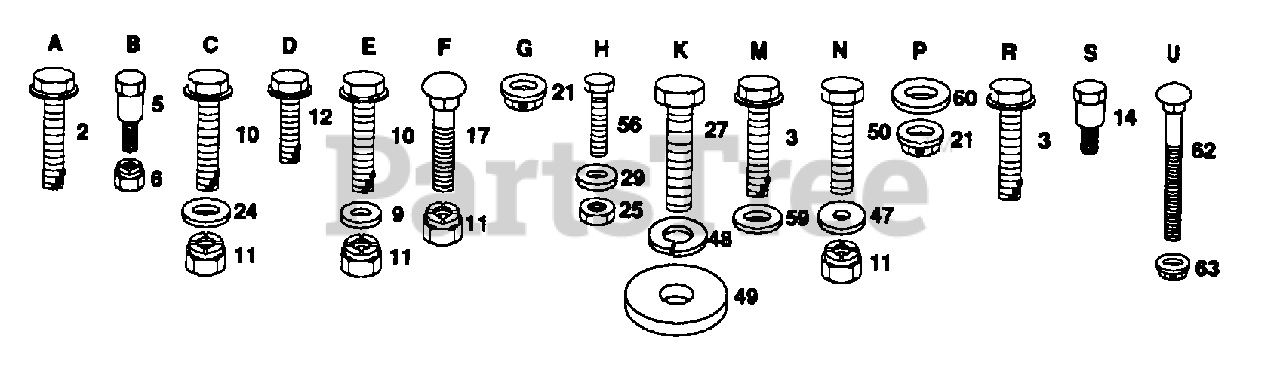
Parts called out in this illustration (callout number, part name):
2	SCREW
3	SCREW GTV
9	WASHER
12	SCREW LT
17	BOLT
21	PAL NUT LT
24	WASHER
25	NUT
27	BOLT
47	WASHER
48	LOCKWASHER
49	WASHER
50	BOLT
56	SCREW SPECIAL
59	WASHER
60	WASHER PM
62	BOLT
